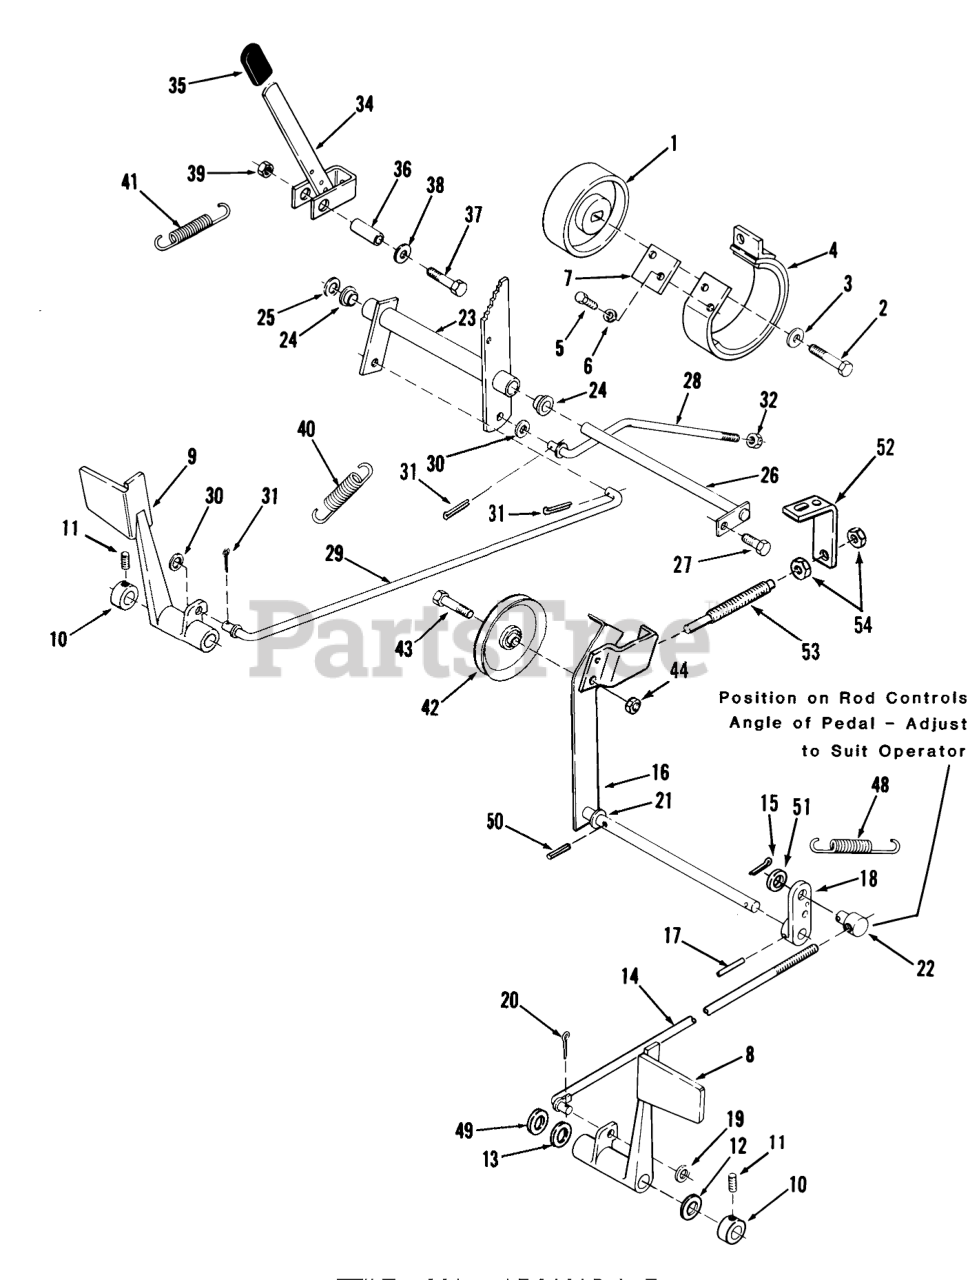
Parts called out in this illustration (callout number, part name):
1	DRUM-BRAKE
2	SCREW-HEX HD CAP
3	WASHER
4	BRAKE BAND ASM
5	H H C S
6	Washer
7	Plate-Stop
8	Pedal-Clutch
9	Pedal Brake
10	Collar
11	SCREW-SET
12	WASHER-BOWED
13	WASHER
14	ROD AND GUIDE ASM
15	Cotter Pin
16	ASSY-IDLER ARM R
17	PIN-SPIROL
18	Arm-Clutch Rod
19	WASHER-NYLON
20	Pop Rivet
21	SHIM-WASHER
22	TRUNNION
23	Bellcrank Assy
24	BUSHING-FLANGED
25	Washer
26	ROD ASM
27	SCREW
28	ROD-REAR BRAKE
30	WASHER-NYLON
31	Pop Rivet
32	NUT
34	ASSY-BRAKE LEVER WAB
35	GRIP
36	SPACER
37	Bolt
38	Washer
39	LOCKNUT-FLANGE
40	SPRING-BRAKE
41	SPRING-EXTENSION
42	PULLEY-IDLER
43	BOLT-SPECIAL HEX
44	Nut
48	SPRING-CLUTCH
49	Washer
50	PIN-SPIROL
51	Washer
52	BRKT-DAMPER B
53	Damper Cylinder
54	Nut
